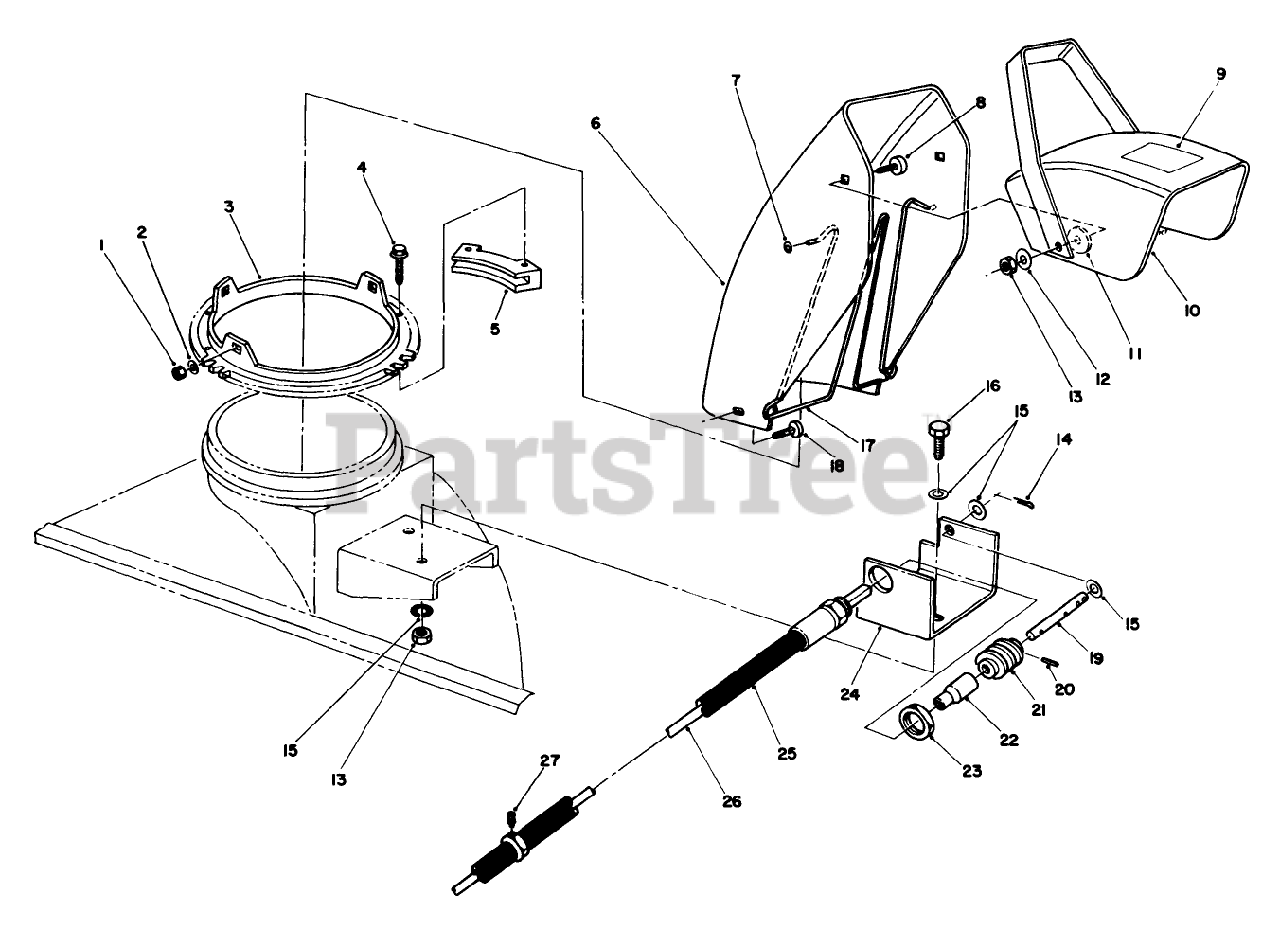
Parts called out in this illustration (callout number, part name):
1	NUT-LOCK, NI
2	WASHER-PLAIN
3	Screw
4	SCREW-SPECIAL
5	RETAINER-CHUTE
6	Chute-Upper
7	NUT-PUSH
8	SCREW-CARR
9	Decal-Discharge
10	Deflector
11	WASHER-RUBBER
12	WASHER-BELLEVILLE
13	NUT-LOCK, NI
14	PIN-COTTER
15	WASHER-FLAT
16	SCREW-HH
17	CHUTE WIRE
18	SCREW-CARR
19	SHAFT-GEAR, WORM
20	PIN-SPRING
21	GEAR-WORM, CHUTE
22	COUPLER
23	LOCKNUT
24	WORM GEAR BRKT R
25	HOSE ASM
26	FLEX SHAFT
27	FITTING-GREASE
